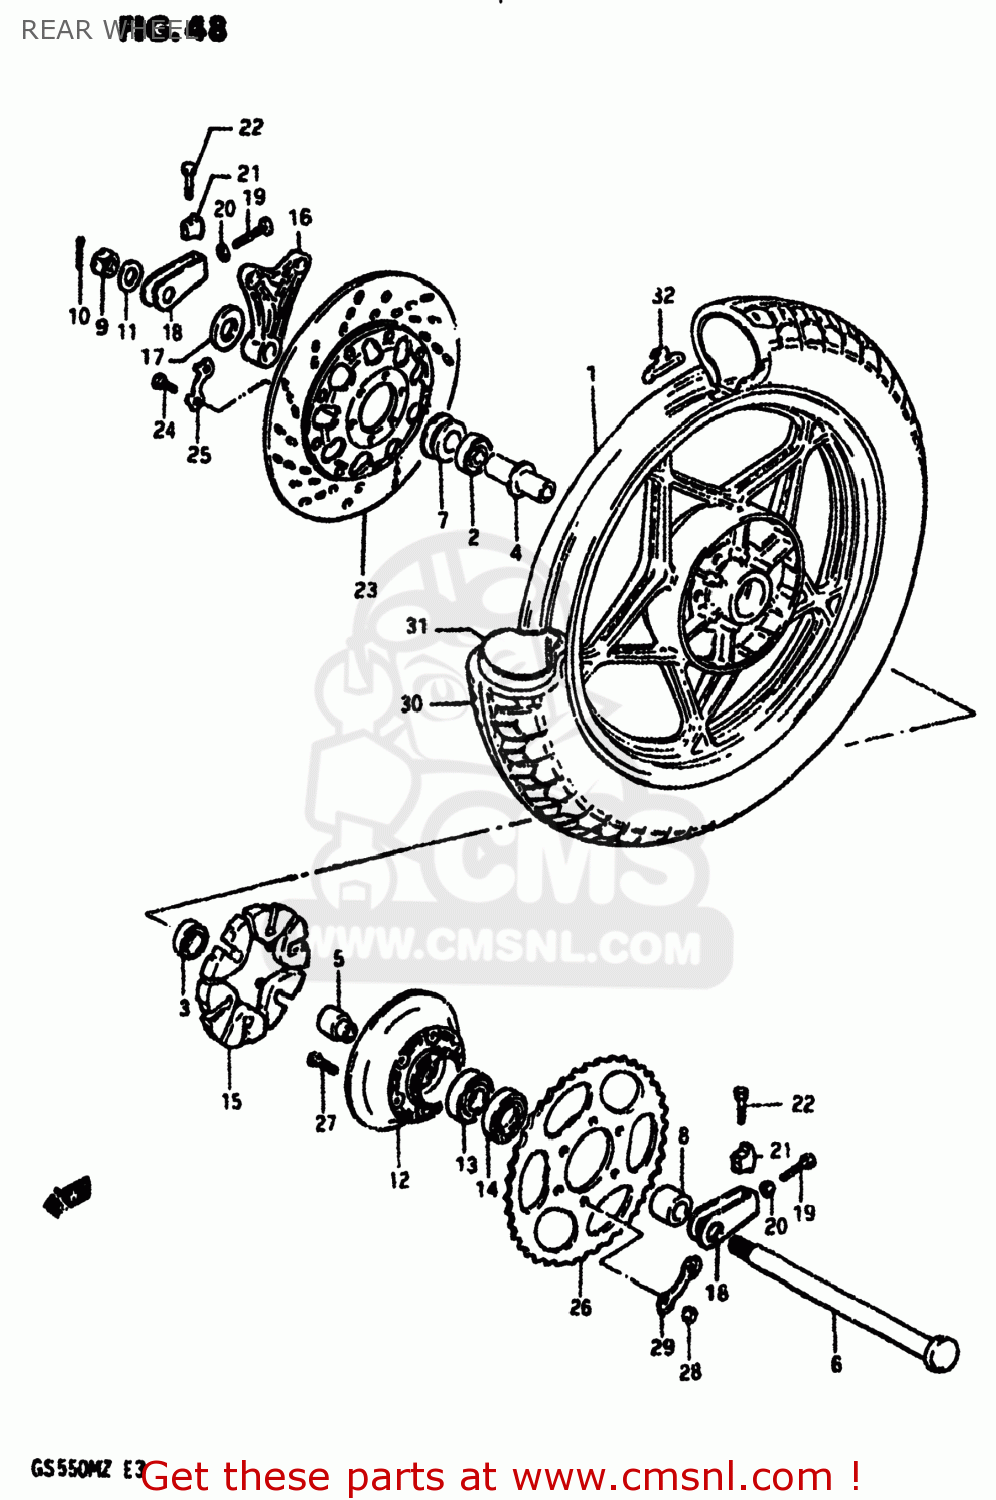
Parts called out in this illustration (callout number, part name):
1	CASTING WHEEL,REAR 2.15
2	BEARING
3	BEARING
4	SPACER,REAR HUB BEARING
5	RETAINER,REAR SPROCKET D
6	AXLE,REAR
7	SPACER,REAR AXLE
8	SPACER (17X33X21.1)
9	NUT
10	PIN,COTTER
11	WASHER (17X30X3.2)
12	DRUM,REAR SPROCKET MOUNT
13	BEARING
14	SEAL,OIL(33X62X7)
15	ABSORBER,REAR HUB SHOCK
16	BRACKET,RR,CALIPER
17	SPACER,REAR CARIPER BRACKET
18	ADJUSTER,CHAIN
19	BOLT 8X50
20	NUT
21	SUPPORTER,CHAIN ADJUST
22	BOLT
23	DISC,BRAKE
24	BOLT(8X30)
25	WASHER
26	SPROCKET,RR
27	BOLT
28	NUT
29	WASHER
30	TIRE
31	TUBE ASSEMBLY,WHEEL,INNER
32	BALANCER,WHEEL
